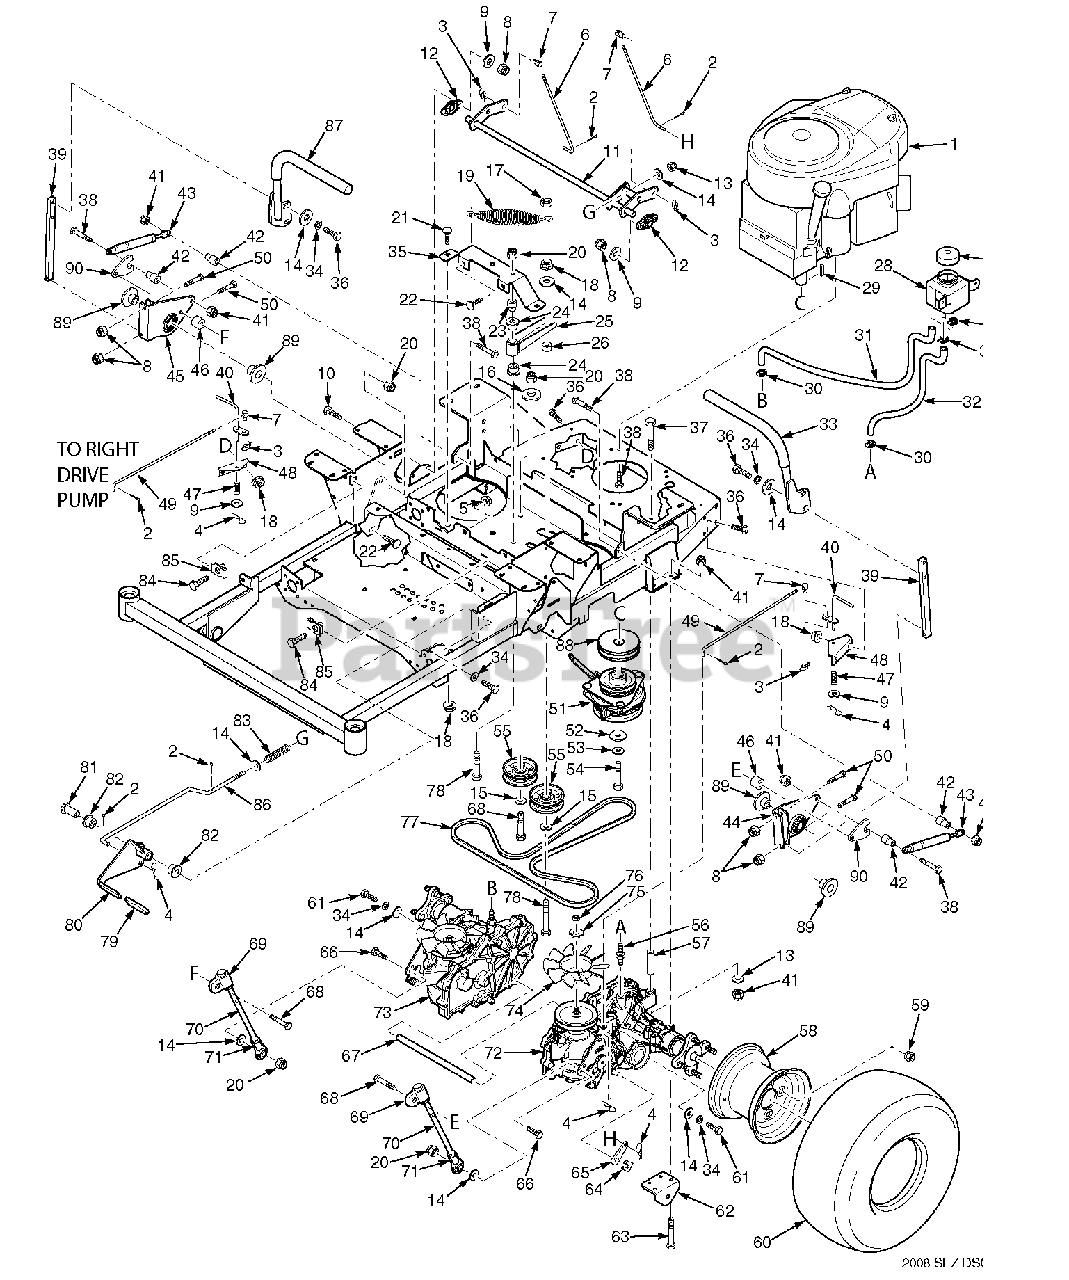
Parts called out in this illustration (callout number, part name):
1	Engine
2	Cotter Pin, 3/32 x 1"
3	Pin, Rue Cotter 3/8" Dia.
4	Hair Pin, .080 x 1.19"
5	Nut, Serrated Flange 5/16-18
6	Rod, Brake Adjustment
7	Joint, Swivel
8	Nut, Elastic Stop 1/4-20
9	Flatwasher, 1/4-.312 x .750 x .065
10	Bolt, Serrated Flange 1/4-20 x 1-1/4"
11	Weldment, Brake Lever
12	Bearing
13	Flatwasher, 5/16-.375 x .875 x .083
14	Flatwasher, 3/8-.391 x .938 x .105
15	Flatwasher, 3/8-.391 x .938 x .105 HD
16	Flatwasher, 3/8-.406 x 1.5 x 7 GA.
17	Nut, Center Lock 3/8-16
18	Nut, Serrated Flange 3/8-16
19	Spring, Transmission Idler
20	Nut, Elastic Stop 3/8-16
21	Bolt, Carriage 3/8-16 x 3/4"
22	Bolt, Carriage 5/16-18 x 3/4"
23	Shaft Pivot, Idler Arm
24	Bearing
25	Transmission Idler Arm Assembly
26	Spacer, Idler Pulley
28	Reservoir Assembly
29	Key, 1/4 x 1/4 x 1-3/4"
29	Key, 1/4 x 1/4 x 2-1/4" - SFZ
30	Clamp, 0.87" Max Dia.
31	Hose, RH Transmission
32	Hose, LH Transmission
33	Handle Bar Assembly, w/Grip
34	Lockwasher, 3/8" Spring
35	Support, Idler Arm
36	Bolt, Hex Head 3/8-16 x 1"
37	Bolt, Hex Head 5/16-18 x 5"
38	Bolt, Hex Head 5/16-18 x 1-1/2"
39	Bar, Control Lever
40	Dump Valve Lever
41	Nut, Elastic Stop 5/16-18
42	Spacer, Pump Dampener
43	Dampener
44	Control Link, LH
45	Control Link, RH
46	Spacer
47	Spring
48	Bracket, Dump Mounting
49	Linkage, Dump Valve
50	Bolt, Hex Head 1/4-20 x 1-1/2"
51	Electric Clutch Assembly
52	Flatwasher, 7/16-.469 x 1.75 x .25
52	Spacer, Crankshaft, SFZ-61
53	Lockwasher, 7/16" spring
54	Bolt, Hex Head 7/16-20 x 2-1/4" Patch
54	Bolt, Hex Head 7/16-20 x 1-1/2" Patch SFZ-61
55	Pulley, 3-1/2" Dia.
56	Fitting, Transmission
57	Spacer, Axle
58	Rim w/Valve Stem
59	Wheel Nut, 1/2-20
60	Wheel Assembly
60	Tire, 20 x 10-8 2-Ply
61	Bolt, Hex Head 3/8-16 x 2-1/4"
62	Bracket, Pusharm Link
63	Bolt, Hex Head 5/16-18 x 3"
64	Clip, Brake Lever
65	Lever, Brake
66	Bolt, Hex Head 3/8-16 x 1-1/4"
67	Spacer, Axle
68	Bolt, Hex Head 3/8-16 x 2"
69	Rod End, Adjustable
70	Linkage, Pump
71	Stake, Rod End Assembly
72	Transaxle Assy.
73	Transaxle Assy.
74	Fan
75	Fan Washer
76	Fan Nut
77	Belt, TRansmission Drive
78	Bolt, Hex Head 3/8-16 x 3"
79	Grip, Brake Handle
80	Brake Handle Assembly
81	Spacer, Brake Handle
82	Bearing
83	Spring, Brake
84	Bolt, Hex Head 3/8-16 x 1-1/4" Special Lock
85	U-Nut, 3/8-16
86	Rod, Brake Linkage
87	Handle Bar w/Grip
88	Pulley, 4-1/2" Dia. 1" Bore
89	Spacer, Linkage
90	Nut, Control Linkage
